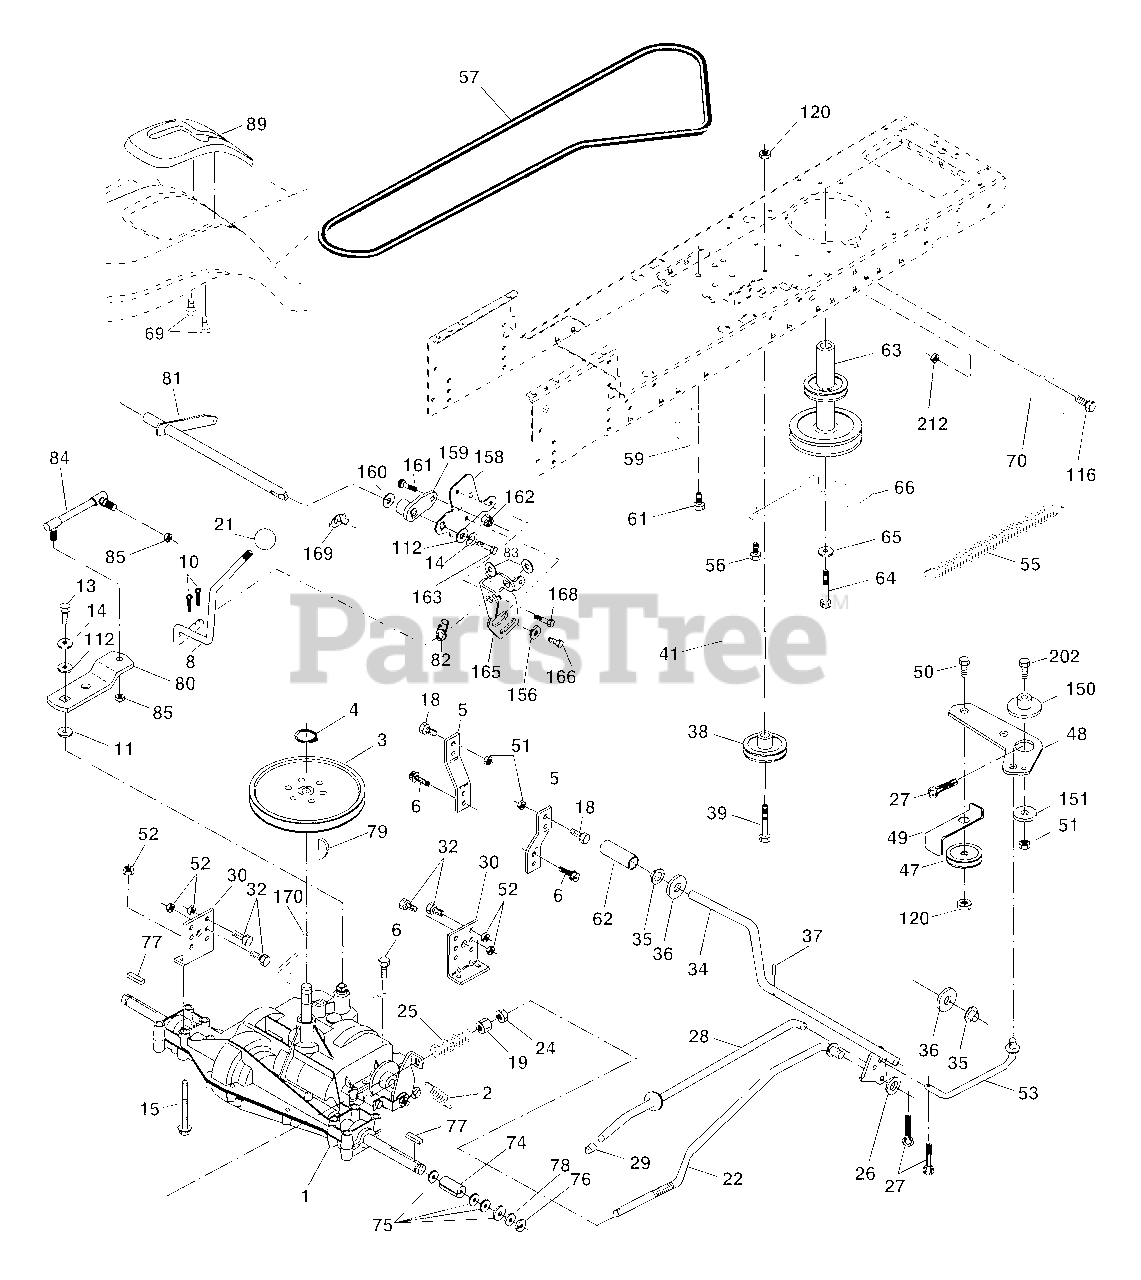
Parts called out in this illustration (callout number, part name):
2	Spring Return Brake T/a Zinc
3	Pulley Transaxle 18" tires
4	Ring Retainer # 5100-62
5	Strap Torque 30 Degrees
6	Screw Thdrol 5/16-18 x 3/4 TYT
8	Rod Shift Fender Adjust STLT
10	Pin Cotter 1/8 x 1 Cad
11	Washer Plate Shf 388 Sq Hole
13	Bolt 1/4-28 unf Gr. 8 W/Patch
14	Washer Lock Hvy Helical 1/4
15	Bolt 5/16-18 Gr. 5
16	Nut Lock Hx W/Ins 5/16-18 unc Pl
18	Bolt, Fin Hex 3/8-16 unc x 1 Gr. 5
19	Nut Lock 3/8-16 unc
22	Rod Brake Blk Zinc 26 840
24	Nut Hex Jam 3/8-16 unc
25	Spring Rod Brake 2 00 Zinc
26	Washer 13/32 x 13/16 x 16 Ga
27	Pin Cotter 1/8 x 3/4 Cad
28	Rod Brake Parking LT/YT
29	Cap Brake Parking Black
30	Bracket Mtg Transaxle
32	Bolt Hex Hd 5/16-18 unc x 3/4
34	Shaft Asm Pedal Foot
35	Bearing Nylon Blk 629 Id
36	Washer 21/32 x 1 x 16 Ga
37	Pin Roll 3/16 x 1"
38	Pulley Composite
39	Bolt Rdhd 3/8-16 x 2-3/4 Gr. 5
41	Keeper Belt Idler Flat
47	Pulley Idler V Groove Plastic
48	Bellcrank Clutch Grnd Drv Stl
49	Retainer Belt Style Spring
50	Bolt Carr. sh 3/8-16 x 1-1/2 Gr. 5
51	Nut Crownlock 3/8-16 unc
52	Nut Crownlock 5/16-18 unc
53	Link Clutch
55	Spring Return Clutch 6 75
56	Screw 3/8-16 x 1-1/4
57	V-Belt Ground Drive 95 25
59	Keeper Belt Span Ctr
61	Screw 3/8-16 x .875
62	Cover Pedal
63	Engine Pulley LT/YT
64	Bolt Hex
65	Washer Lock Hvy Hlcl Spr 7/16
66	Keeper Belt Engine Foolproof
69	Screw Hex Wsh Hi-Lo 1/4-1/2 unc
70	Guide Belt Mower Drive RH
74	Spacer Axle
75	Washer 25/32 x 1 1/4 x 16 Ga.
76	E-ring #5133-75
77	Key Square 2 0 x 1845/ 1865
78	Washer 25/32 x 1-5/8 x 16 Ga.
79	Key Woodruff #9 3/16 x 3/4
81	Shaft Asm Cross Tapered DA/PR 18"
82	Spring Torsion T/a
83	Washer 17/32 x 3/4 x 16 Ga.
84	Transaxle Link
85	Nut Lock Center 1/4 - 28 FNTHD
89	Console Shift STLT
96	Retainer Spring 1"
112	Washer 9/32 x 3/4 x 10 Ga.
113	Strap Torque LT
116	Bolt Rdhd Sq Neck 3/8-16 x 1
120	Nut Lock Flg. 3/8-16
150	Spacer Retainer
151	Washer 13/32 x 2 x 10 Ga.
156	Washer Srrted 5/16 ID x 1.125
158	Bracket Shift Mount
159	Hub Shift
161	Bolt Rdhd Sqnk 1/4-20 x 3/4 Gr. 5
162	Nut Crownlock 1/4-20 unc
163	Bolt Hex Fin 1/4-20 unc x 1 Gr. 5
165	Bracket Pivot Lever
166	Screw 5/16-18 x 5/8
168	Bolt Shoulder 5/16-18 x .561
169	Plate Fastening STLT/CRD
170	Keeper Belt T/A
197	Nyliner Snap-In 5/8" ID
198	Washer Nyl 7/8 Id x .105" Hyd
202	Bolt 3/8-16 x 1-3/4 Gr 5
212	Nut Hex Flg Lock
